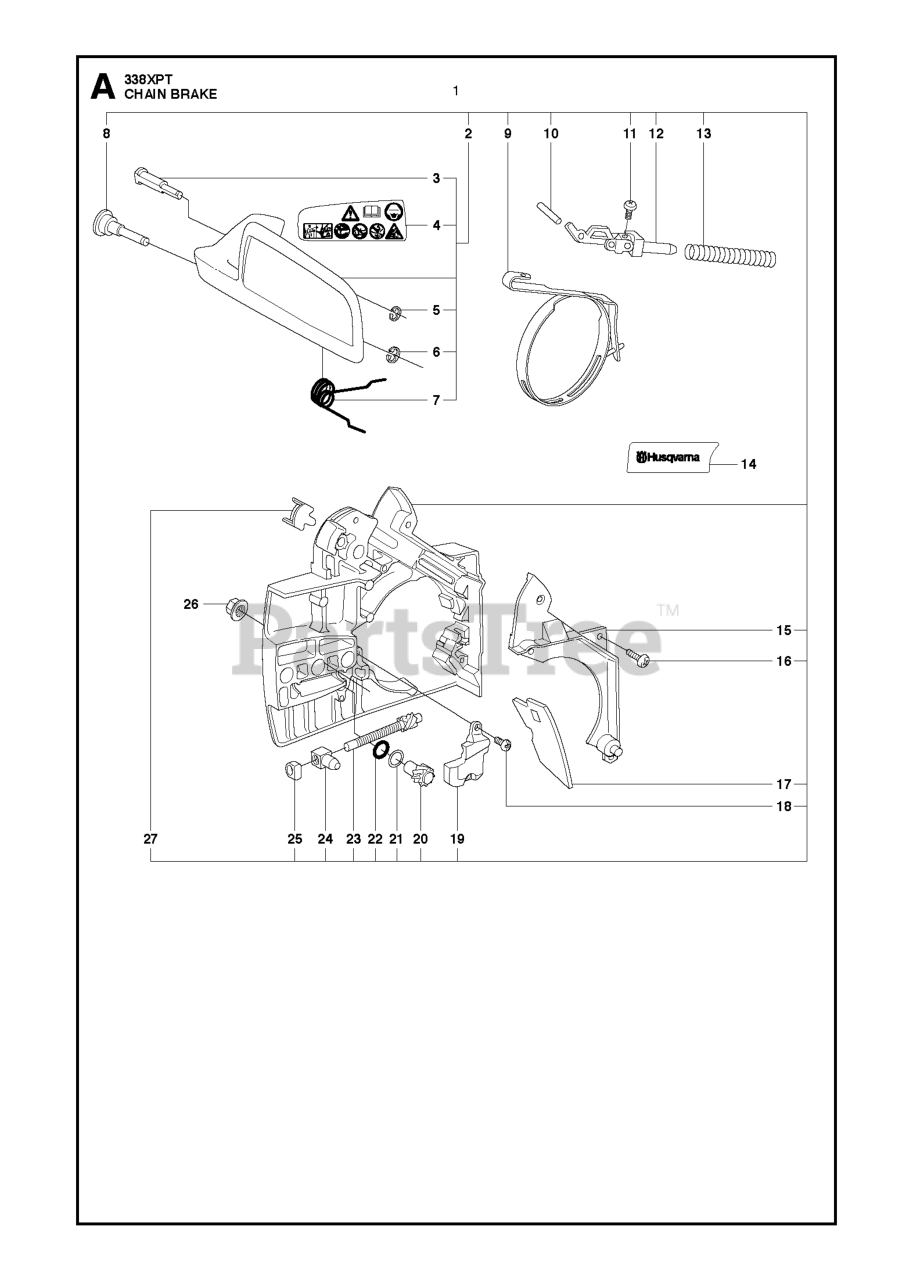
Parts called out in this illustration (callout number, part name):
1	BRAKE ASSY
2	HAND GUARD ASSY
4	LABEL WARNING
7	POSITION SPRING
8	SHAFT PIVOT
9	BRAKE BAND ASSY
12	KNEE-JOINT
13	SPRING
20	WORM WHEEL
24	PIN BAR ADJUSTING
26	NUT M8 FLANGE
